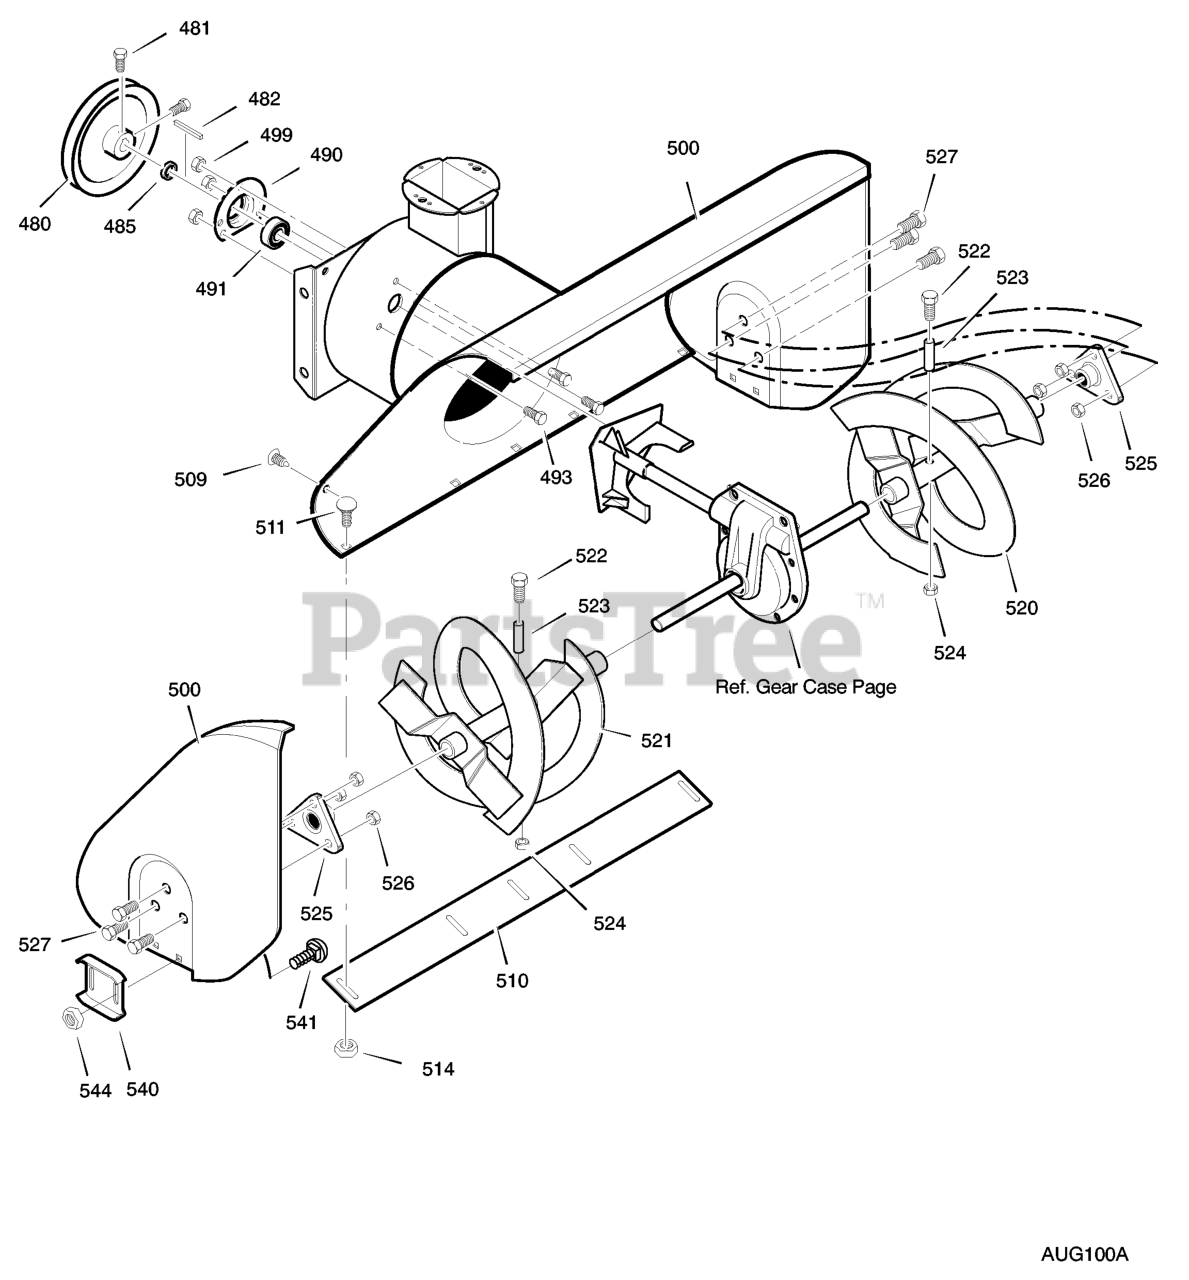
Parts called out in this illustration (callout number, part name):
480	PULLEY, 4L 8.4 X .67 HYBRID
481	SCREW, 5/16-18 x 0.62
482	KEY, SQUARE 3/16 X 3/4
485	SPACER, FRICTION PULLEY
490	RETAINER, BALL BRNG
491	BEARING, BALL
493	BOLT, HEX 5/16-18X .50
499	NUT, 5/16-18 HEXWDFLLK
500	HOUSING, ASSY
509	PLUG, CHRISTMAS TREE
510	BLADE, SCRAPER
511	BOLT, 5/16-18X.75
514	NUT, 5/16-18
520	AUGER, ASSY, LH
521	AUGER, ASSY, RH
522	SCREW, 1/4-20X1.75
523	SPACER, SLEEVE
524	NUT, 1/4-20
525	BEARING,FLANGE
526	NUT, 5/16-18
527	SCREW, 5/16-18 x 0.75
540	SKID, HEIGHT ADJUST
541	BOLT, 5/16-18 X .75
544	NUT, 5/16-18
